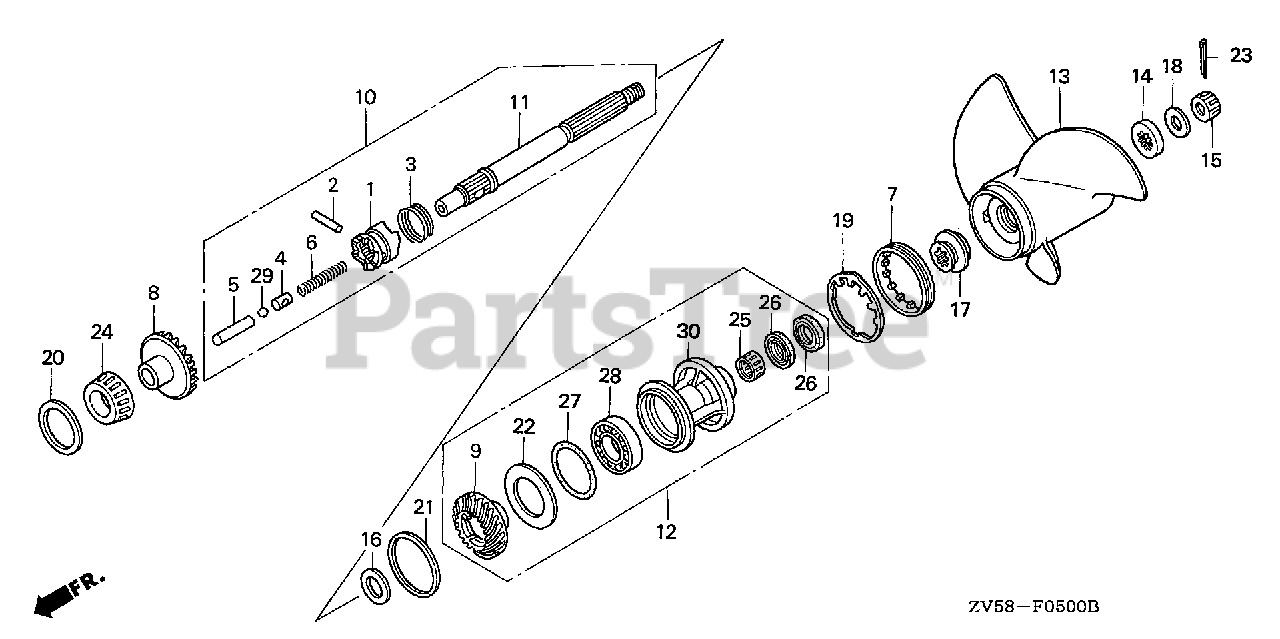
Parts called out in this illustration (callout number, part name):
1	SHIFTER, CLUTCH
2	PIN, SHIFTER (6.3X33)
3	RING, CROSS PIN
4	HOLDER, SHIFTER PIN
5	SLIDER, SHIFT
6	SPRING, SHIFT
7	NUT, GEAR CASE END
8	GEAR, FR. BEVEL
9	GEAR, RR. BEVEL
10	SHAFT ASSY., PROPELLER
11	SHAFT, PROPELLER
12	HOLDER ASSY., PROPELLER SHAFT
13	PROPELLER, THREE-BLADE (11-1/4X13) *NH283* (STIN GRAY)
13	PROPELLER, THREE-BLADE (11-1/2X12) *NH283* (STIN GRAY)
13	PROPELLER, THREE-BLADE (11-3/4X10) *NH283* (STIN GRAY)
13	PROPELLER, THREE-BLADE (11-1/2X14-1/4) *NH283* (STIN GRAY)
14	SPACER (10MM)
15	NUT, CASTLE (16MM)
16	WASHER (22MM)
17	WASHER, PROPELLER THRUST
18	WASHER (17MM)
19	WASHER, CLAW
20	SHIM, FR. BEVEL (51X57X0.10) (A)
20	SHIM, FR. BEVEL (51X57X0.15) (B)
20	SHIM, FR. BEVEL (51X57X0.30) (C)
20	SHIM, FR. BEVEL (51X57X0.50) (D)
21	SHIM, RR. BEVEL (73X77X0.10) (A) (NOT AVAILABLE)
21	SHIM, RR. BEVEL (73X77X0.15) (B) (NOT AVAILABLE)
21	SHIM, RR. BEVEL (73X77X0.30) (C)
21	SHIM, RR. BEVEL (73X77X0.50) (D)
22	WASHER, PLAIN (54MM)
23	PIN, COTTER (4.0)
24	BEARING (32X58X17)
25	BEARING, NEEDLE (22X28X20)
26	SEAL, WATER (22X35X7)
27	O-RING (66X5.7)
28	BEARING, RADIAL BALL (6007)
29	BALL, STEEL (#11) (11/32)
30	HOLDER, PROPELLER SHAFT
